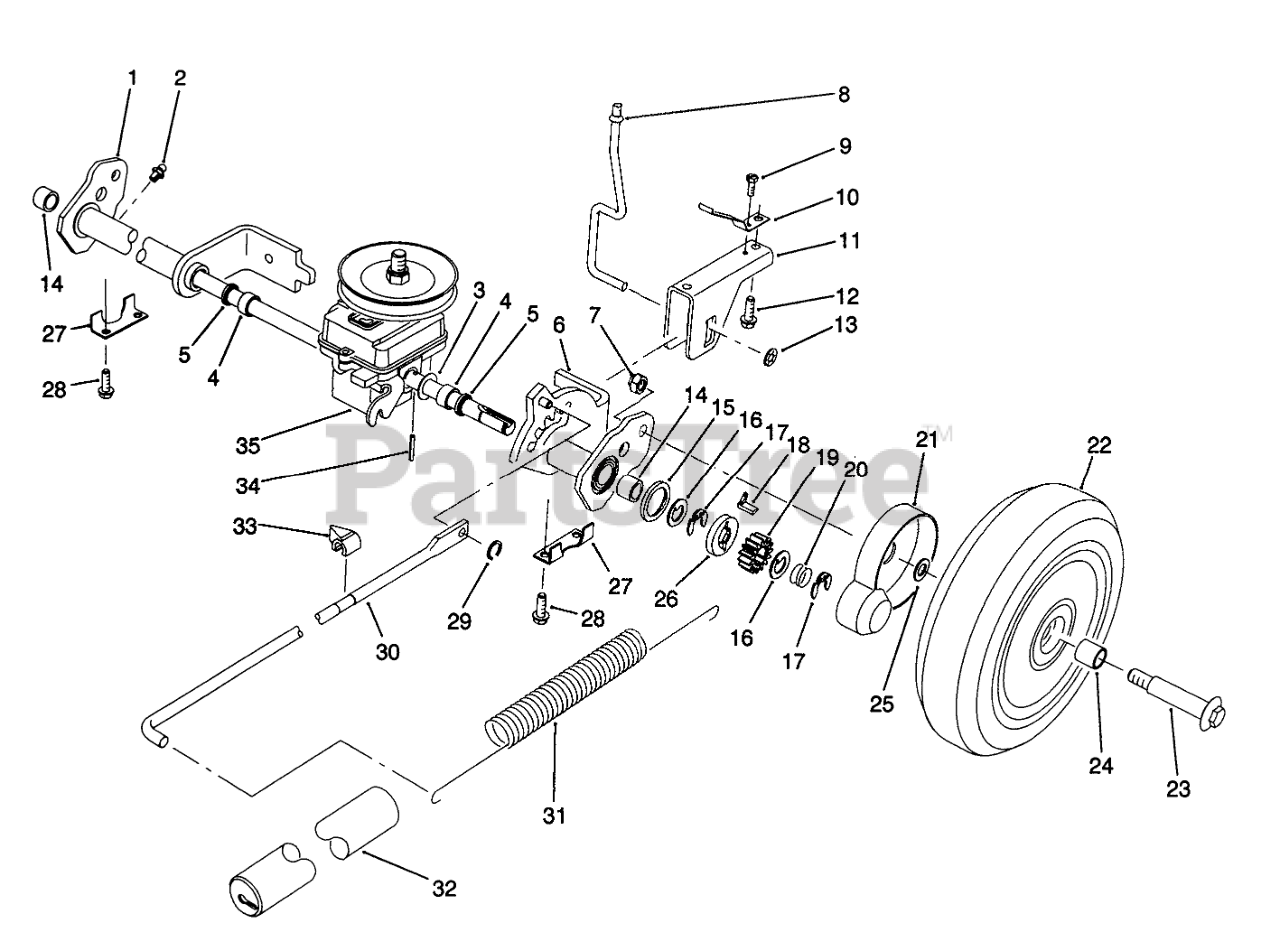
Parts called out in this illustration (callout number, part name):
1	Rear Pivot Assembly R.H. (Incl. Ref. #2, 4, 5 & 14)
2	FITTING-GREASE
3	WASHER-PLAIN
4	BUSHING
5	SEAL-OIL
6	Rear Pivot Assembly L.H. (Incl. Ref. #2, 4, 5 & 14)
7	Nut
8	TRIGGER ROD
9	SCREW 8 - 32 X 250
10	SPRING - TRIGGER RET
11	SADDLE - HOC
12	SCREW
13	PUSHNUT
14	BEARING-ROLLER
15	RING-FRICTION
16	WASHER-THRUST, KEYED
17	RING-CLIP, LOCKING
18	KEY-ROCKING, LH
19	GEAR-PINION
20	SPRING-COMPRESSION
21	COVER-WHEEL
22	Wheel, Tire & Gear Assy. (Incl. Ref. #24)
23	BOLT-WHEEL
24	BUSHING
25	SPACER-COVER, WHEEL
26	WASHER-CLUTCH
27	REAR SECURING PLATE
28	SCREW-HWHTF
29	GRIP RING
30	LINK ROD
31	SPRING-COUNTERBALANCE
32	COVER-SPRING
33	INDICATOR-HEIGHT OF CUT
34	COIL PIN
35	Gearbox Assembly
